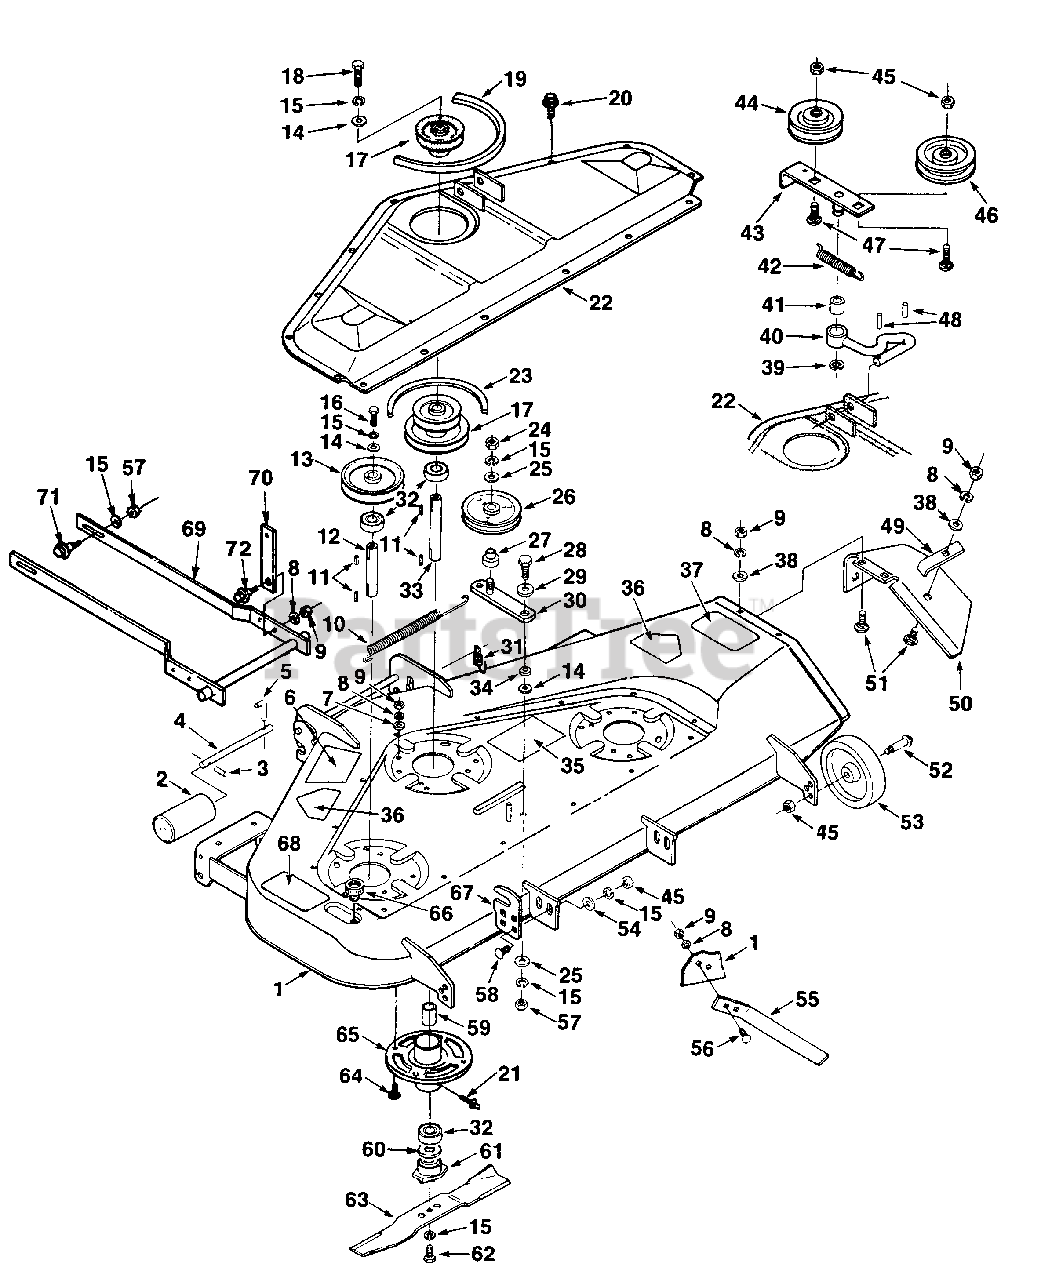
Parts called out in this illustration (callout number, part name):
1	MOWER HOUSING ASSEMBLY
3	PIN- 3/16 x 13/16 roll
4	SHAFT- Front roller
5	PIN- Hold
6	DECAL- Instruction
7	WASHER-5/16 std flat
8	WASHER- Lock 5/16 hvy
9	NUT- Hex 5/16-18
10	SPRING- Idler pulley
11	KEY- Parallel 3/16 x 3/16 x 13/16
12	SHAFT- Cutter sides
13	PULLEY- R.H. & L.H. Cutter drive
14	WASHER- Pulley retainer
15	WASHER- Lock 3/8 hvy
16	SCREW- 3/8-24 x 1 1/4 Hex hd. cap
17	PULLEY- Mower drive
19	V-Belt engine to mower
20	SCREW- 1/4-20 x 1/2 hex hd. type T
21	FITTING- Grease
22	MOWER PULLEY COVER ASSEMBLY
23	BELT- Cutter drive
24	NUT- 3/8-16 hex jam
25	WASHER- 3/8 SAE flat
26	IDLER PULLEY ASSEMBLY
27	STANDOFF- Idler
28	SCREW- 3/8-16 x 1 1/4 C/R truss hd.
29	WASHER- Arm retaining
30	WELDMENT- Idler arm
31	SPRING- Hitch latch front
32	BEARING- Cutter shaft
33	SHAFT- Cutter center
34	SPACER- Idler arm pivot
35	DECAL- Belt mtg. instruction
36	DECAL- CPSC warning
37	DECAL- Danger
38	WASHER- 5/16
39	RING- Tru-arc 5133-62 retaining
40	IDLER ROD ASSEMBLY
42	SPRING- Extension
43	IDLER PIVOT ASSEMBLY
44	PULLEY- Idler V-groove
45	NUT- 3/8-16 prev. tq. hex L'nut
46	PULLEY- Idler backside
47	BOLT- 3/8-16 x 1 3/4 rd. hd. sq. neck
48	PIN- Roll 1/8 x 7/8
49	BRACKET- Deflector clamping
50	DEFLECTOR- Discharge chute
51	BOLT- 5/16-18 x 3/4 rd. hd. sq. neck
52	BOLT- Shoulder
53	WHEEL- Gauge
55	GUARD- Toe
56	BOLT- 5/16-18 x 7/8 rd. hd. short sq. neck carr
57	NUT- Hex 3/8-16
58	BOLT- 3/8-16 x 1 1/4 rd. hd. sq. neck
59	SPACER- Bearing
60	WASHER- Flat
61	ADAPTER- Blade
62	SCREW- Mach Hex hd 3/8-24 x 1 1/4
63	CUTTER BAR SET
64	SCREW- 5/16-18 x 3/4 hex hd.
65	CUTTER HOUSING ASSEMBLY
66	FITTING- Washout
67	BRACKET- Rear hanger
68	DECAL- Danger
69	DRAG LINK ASSEMBLY
70	LINK LIFT ASSEMBLY
71	BOLT- 3/8-16
72	BOLT- 5/16-18
